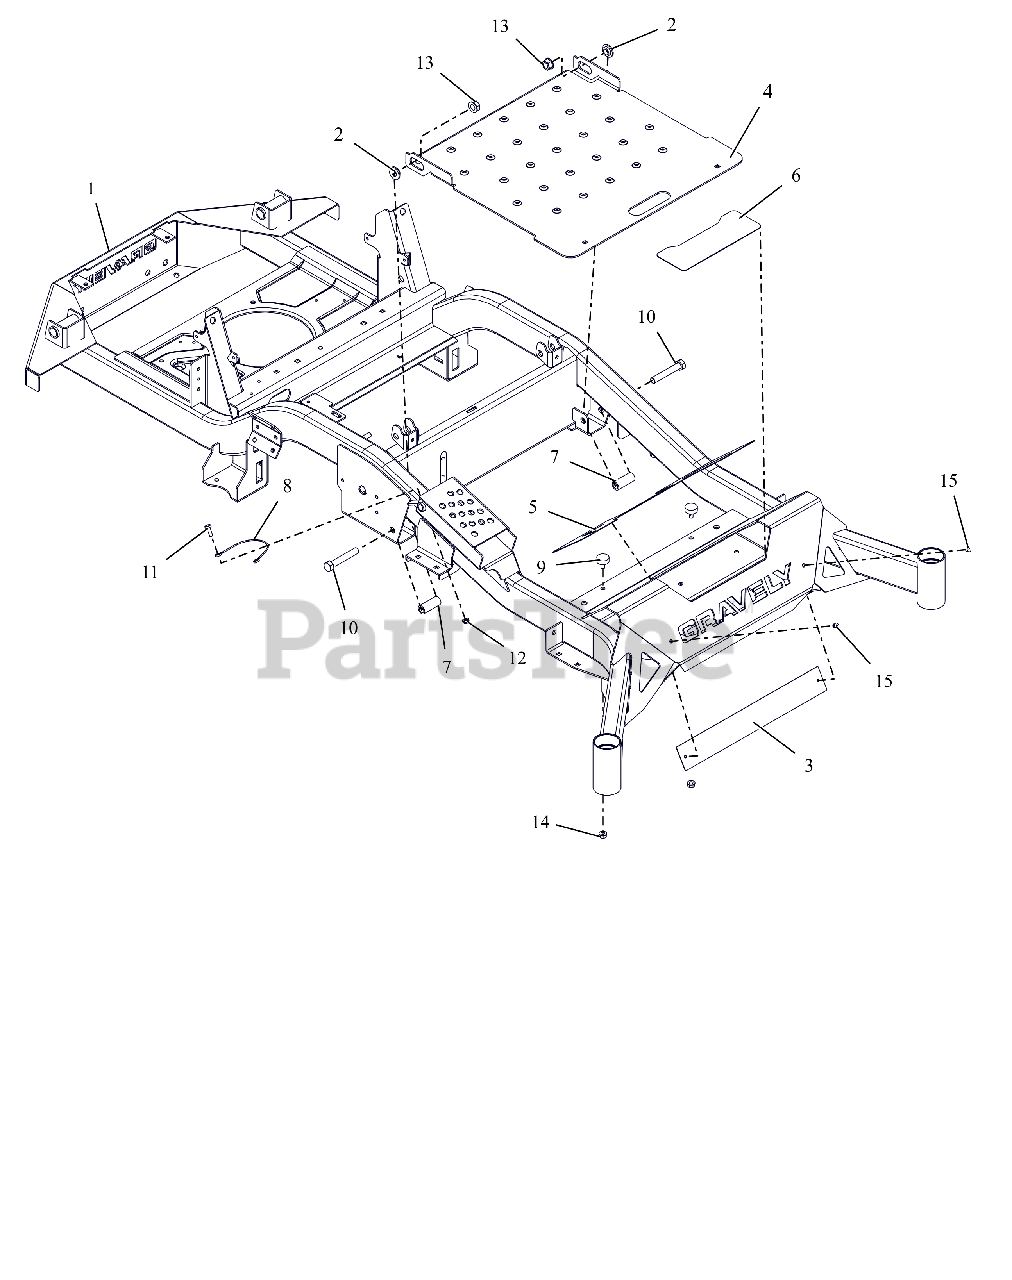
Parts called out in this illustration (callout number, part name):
1	HD 60"FRAME W/SAFETY DECALS
2	BSHG-FLG .515X.750X.310X1.120
3	PLATE, BACK FOOT-REST XL
4	KIT,ACCESS PANEL W/DECALS-RED
5	GRIP, FRONT
6	GRIP, STEP
7	SPACER, .515X.75X1.83
8	CABLE, 12.0 LANYARD, NYLON
9	BUMPER, RUBBER
10	BLT, HEX .50-13X3.00 G5 ZCC
11	BLT, HEX .25-20X.75 G5 ZCC
12	NUT,NYL-FLG .25-20 GF ZCC
13	NUT-LK-TOP-FLG .500-13 GF ZCC
14	NUT,SPNLK-FLG .31-18 G5 ZCC
15	RIVET, .1875 AL/AL .126-.250
